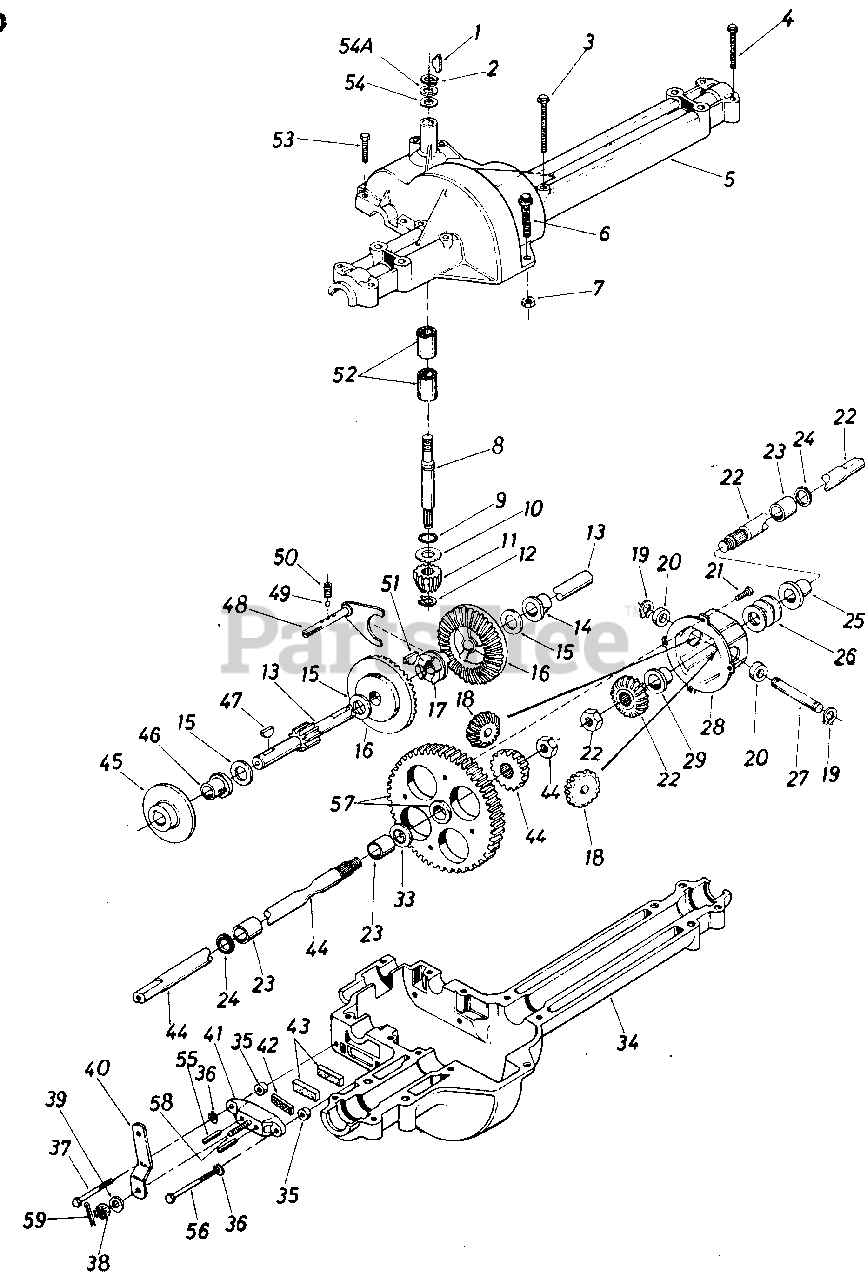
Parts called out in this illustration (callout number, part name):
1	#4 Hi-Pro Key 3/32 x 5/8" Dia.
2	Snap Ring .625" Shaft
3	Hex Bolt 1/4-20 x 1.75" Lg.
4	Hex Bolt 5/16-18 x 2.5"
5	Upper Housing
6	Hex Fl-Bolt 1/4-20 x .88" Lg.
7	Hex Nut 1/4-20 Thd.*
8	Input Shaft
9	Square Seal 5/8" I.D.
10	Thrust Washer 5/8" I.D. x 1.25 O.D.
11	Pinion Input 14T
12	Retaining Ring 7/16" Ext.
14	Flange Brg. 5/8" I.D. x 3/4"- 0 Lg.*
15	Fl-Wash.
16	Bevel Gear 42T
17	Clutch Collar
18	Miter Gear 15T (H.D.)
19	Snap Ring
20	Thrust Bearing 1/2" I.D. x 1.0" O.D.
21	Pan Head Scr. 1/4-20 x .50" Lg. w/Patch
22	Axle R.H. Ass'y.-Kit
23	Sleeve Bearing 3/4" I.D. x 1.0" Lg.
24	Oil Seal 3/4" I.D.
25	Flange Bearing 3/4" I.D. x 15/16" Lg.
26	Fl-Wash. .760" I.D. x 1.49" O.D.
27	Cross Shaft
28	Differential Housing Ass'y.
33	Fl-Wash. .760" I.D. x 1.49" O.D.
34	Lower Housing
35	Spacer .53" O.D. x 3/8" Lg.
36	L-Wash. 1/4" I.D.*
37	Hex Bolt 1/4-20 x 1.50" Lg. (Grade 5)
38	Castle Nut 5/16-24 Thd.
39	Fl-Wash. .344" I.D. x .875" O.D.
40	Actuating Arm
42	Puck Plate
43	Brake Puck
44	Axle L.H. Ass'y.-Kit
46	Flange Bearing 5/8" I.D. x 15/16" Lg.
47	Woodruff Key 3/16 x 5/8 HT
48	Shift Fork Ass'y.
49	Ball Detent .250" Dia.
50	Spring Detent
51	#9 Hi-Pro Key 3/16" x 3/4" Dia. HT
52	Needle Brg. 5/8" I.D. x 1/2" Lg.
53	Hex Bolt 1/4-20 x 1.00" Lg.
54	Fl-Wash. 5/8" I.D. x .030
54A	Fl-Wash. 5/8" I.D. x .040
55	Actuating Pin 5/16" Dia.
56	Hex Bolt 1/4-20 x 2.50" Lg. (Grade 5)
57	Differential Gear 72T Ass'y. w/Bearing
58	Sq. Hd. Bolt 5/16-24 Thd.
59	Cotter Pin 3/32" Dia. x .50" Lg.
